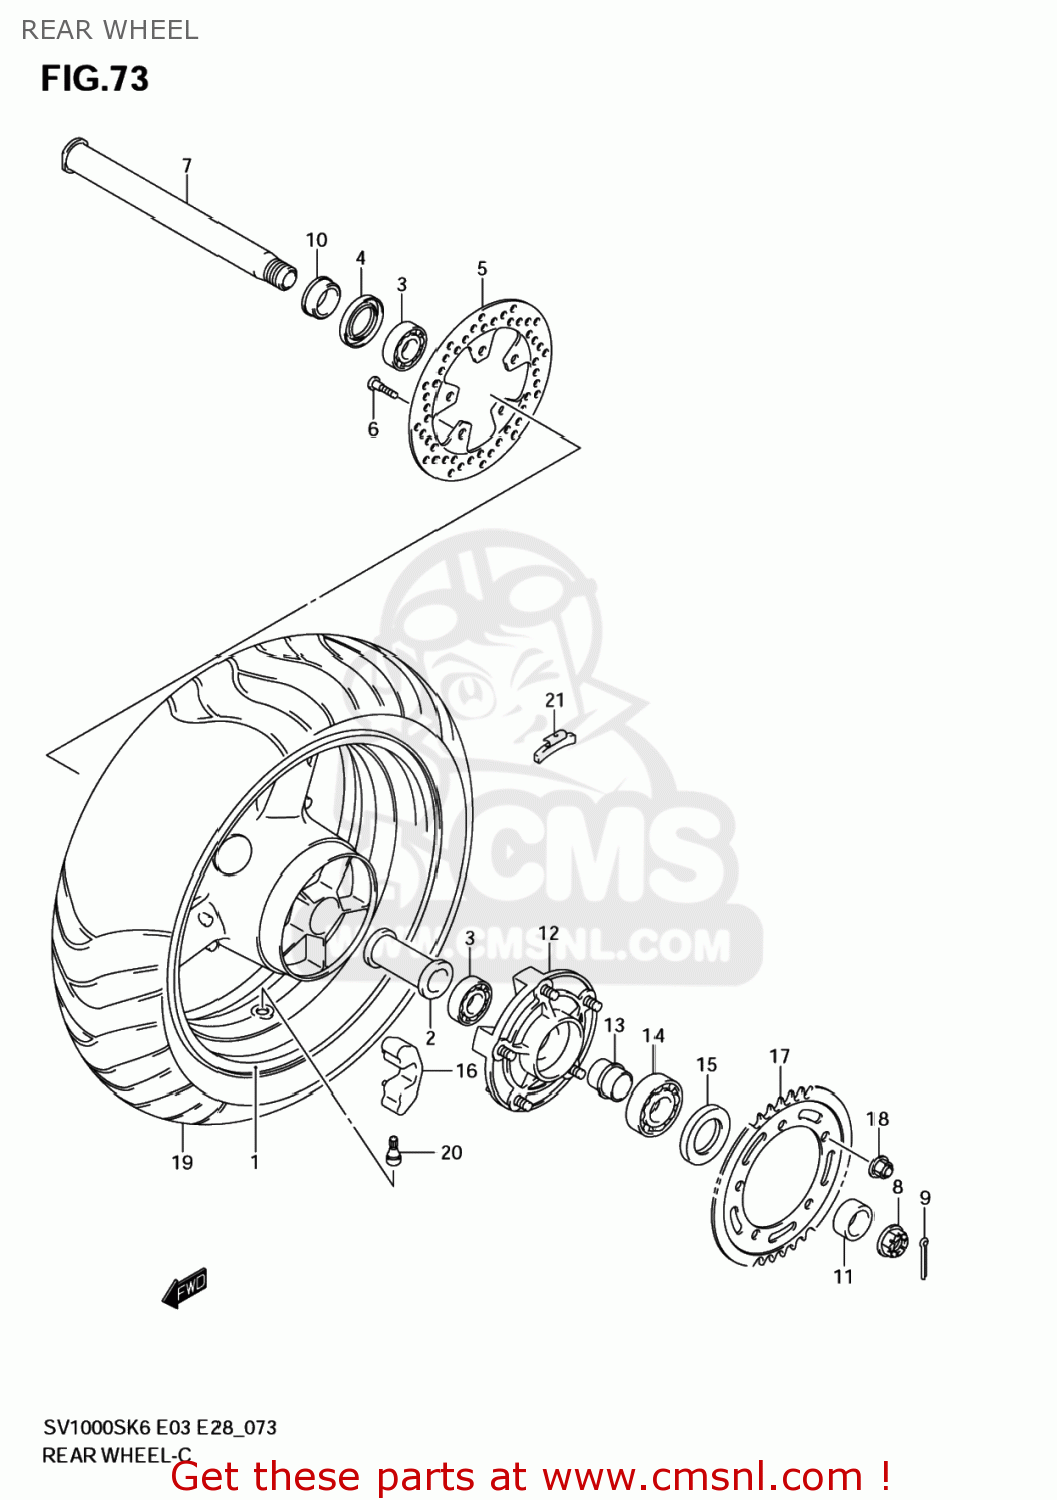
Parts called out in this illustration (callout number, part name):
1	WHEEL,RR(17M/CXMT5.50)
2	SPACER,REAR HUB BEARING
3	BEARING(28X52X12)
4	SEAL,OIL(37X52X8)
5	DISC,RR BRAKE
6	BOLT(8X33)
7	AXLE,RR
8	NUT
9	PIN
10	SPACER,RR AXLE,R
11	SPACER,RR AXLE,L
12	DRUM, REAR SPROCKET
13	RETAINER,RR SPROCKET DRUM
14	BEARING
15	SEAL,OIL(39X65X7)
16	ABSORBER,RR HUB SHOCK
17	SPROCKET,RR(40T-530)
18	NUT
19	TIRE COMP.RR.18
20	VALVE ASSY,WHEEL RIM(TR412)
21	WEIGHT,WHEEL BALANCE 10G
